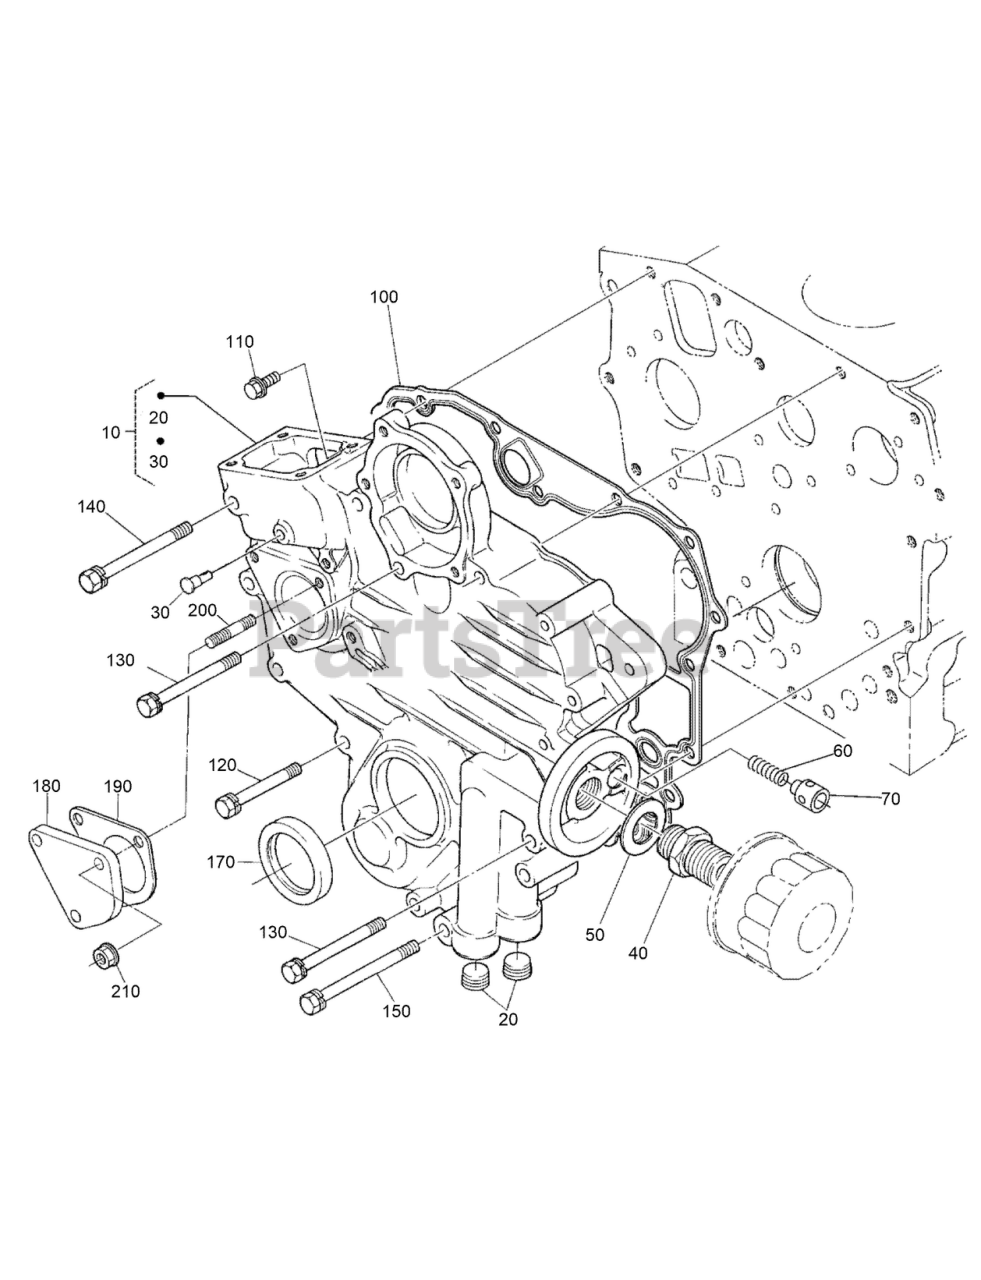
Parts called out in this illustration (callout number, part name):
10	COMP.CASE,GEAR
30	PIN-SPRING, START
40	JOINT-PIPE
50	WASHER-PLAIN
60	SPRING
70	VALVE-RELIEF
100	GASKET,GEAR CASE
110	BOLT-FLANGE
120	BOLT-SEMS
140	BOLT,SEMS
170	SEAL, OIL
190	GASKET
210	NUT-FLANGE
